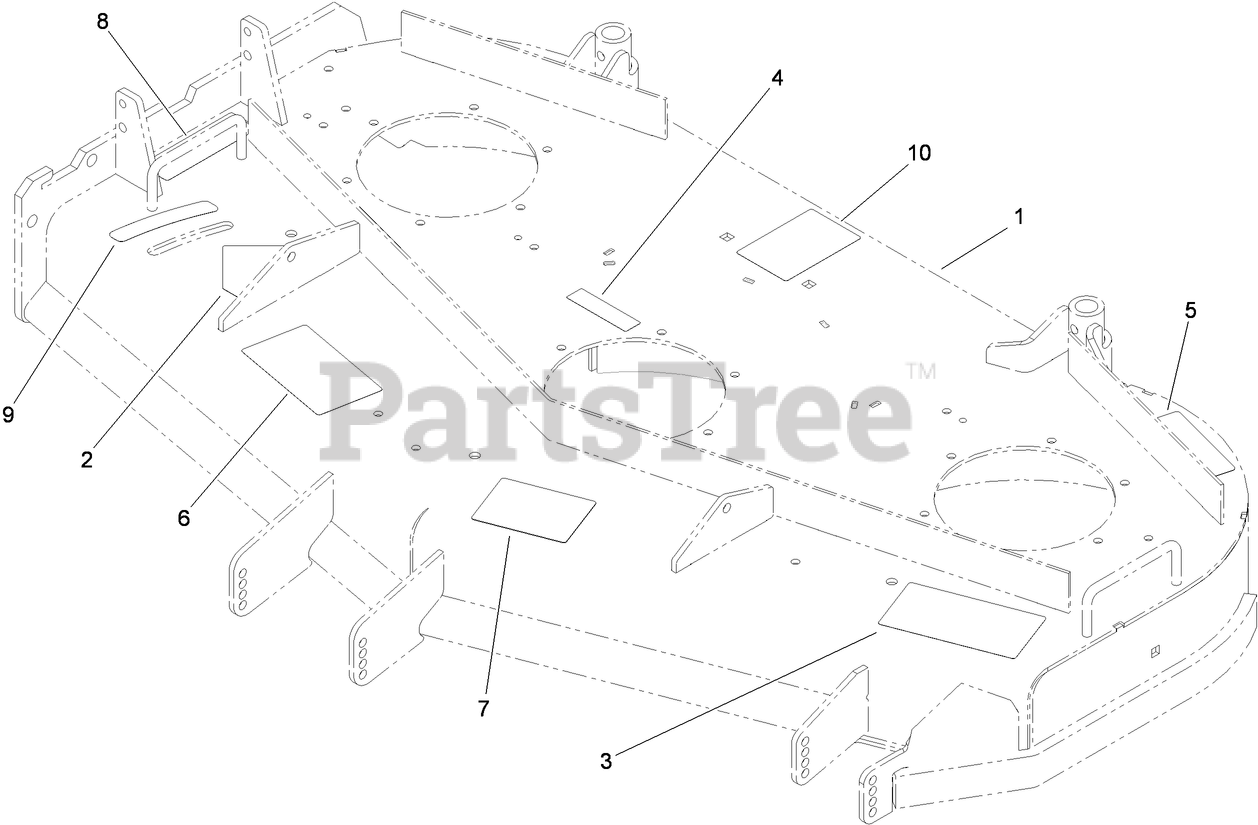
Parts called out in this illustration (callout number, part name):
1	48 INCH DECK ASM
2	DECAL-DANGER
3	DECAL-DANGER, THROWN OBJECT
4	DECAL-COVER, MISSING
5	DECAL-TORQUE
6	DECAL-ADJUSTMENT, BAFFLE
7	DECAL-SCALP, ANTI
8	DECAL-WARNING
9	DECAL-SETTING, BAFFLE
10	DECAL-ROUTING, BELT
